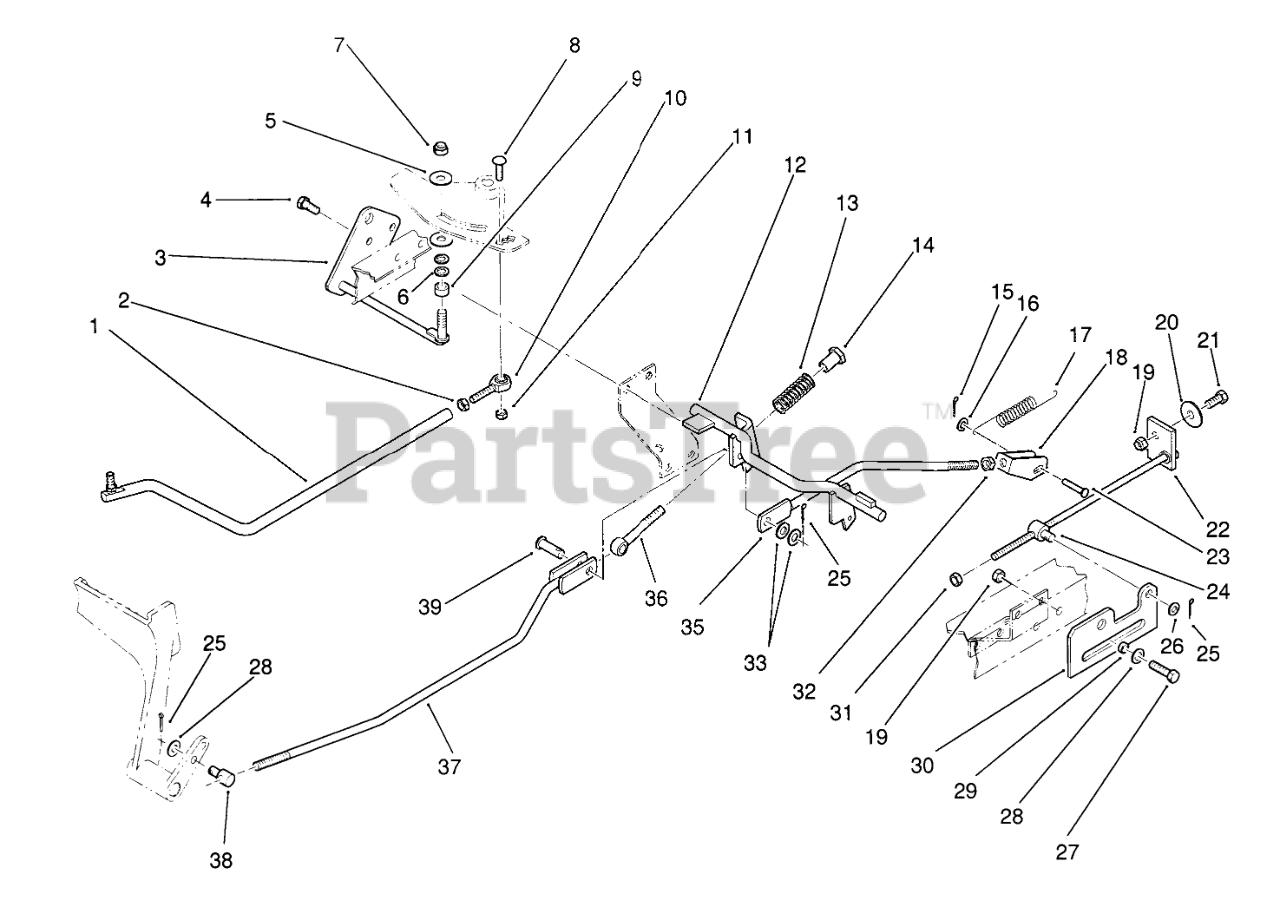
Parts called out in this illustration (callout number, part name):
1	ROD-CONTROL R
2	Nut
3	WLDMT-ROD R
4	Screw
5	FRICTION WASHER
6	WASHER-SPRING DISC
7	NUT
8	Bolt-Carriage
9	SPACER
10	BALL-END
11	Nut
12	WLDMT-NEUTRAL SHA R
13	SPRING-COMPRESSION
14	NUT-RETAINER
15	PIN-COTTER
16	Washer
17	SPRING-EXTENSION
18	WLDMT-CLEVIS
19	Nut
20	WASHER
21	Screw-Cap Hex. Hd.
22	WLDMT-BOLT
23	Pin-Clevis
24	TRUNNION
25	Cotter Pin
26	WASHER-PLAIN
27	Bolt
28	WASHER 5/16 SAE
29	SPACER
30	PLATE R
31	Nut
32	Nut
33	Washer
34	Collar
35	WLDMT-BRAKE ROD R
36	EYE-BOLT
37	WLDMT-BRAKE ROD
38	TRUNNION
39	CLEVIS PIN
